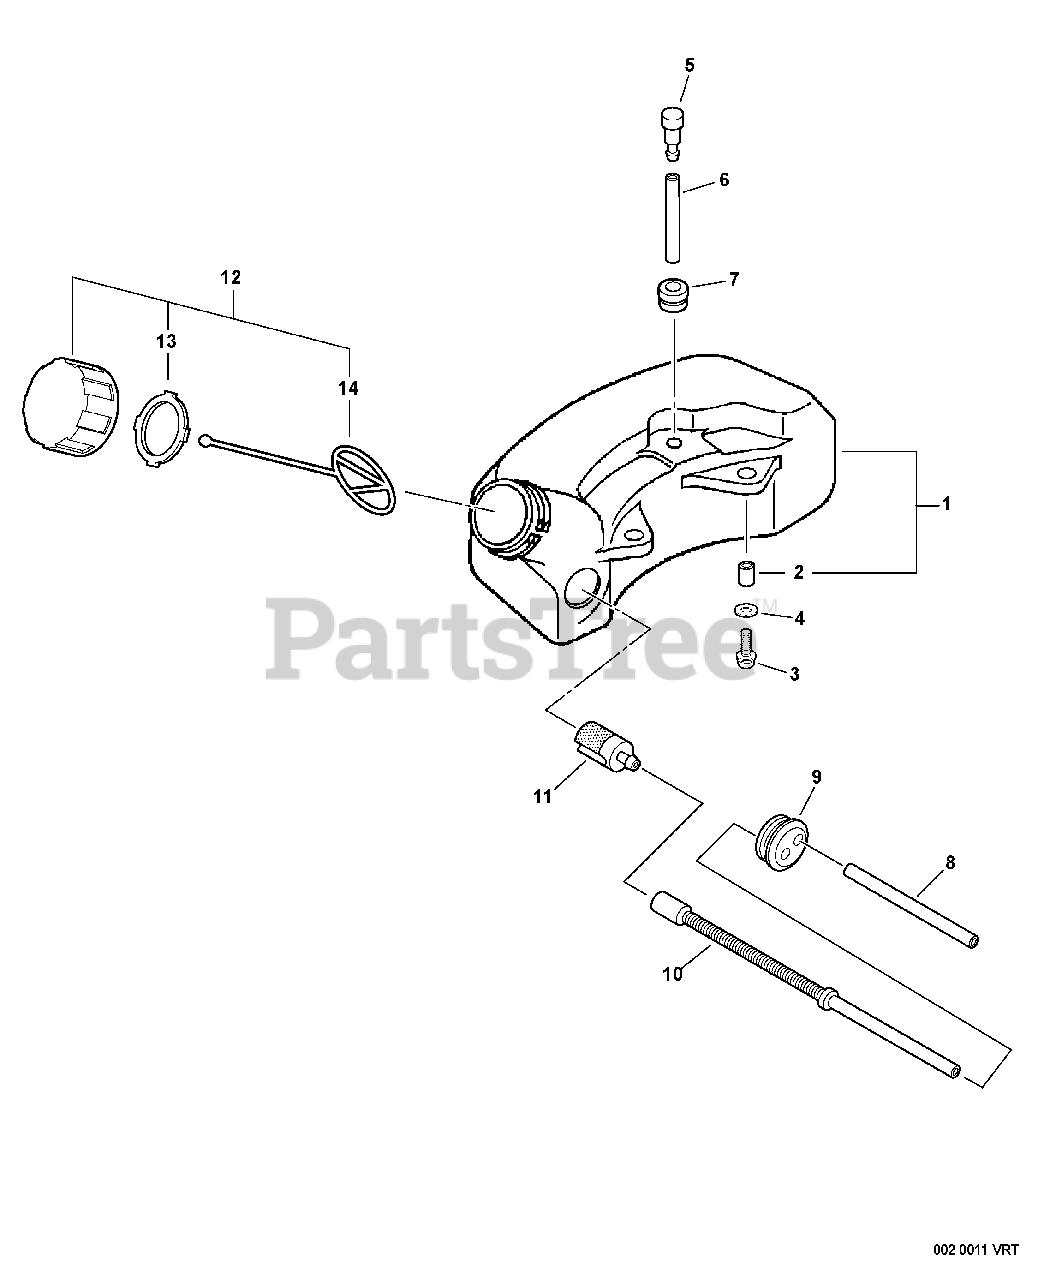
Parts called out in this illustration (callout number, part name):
1	TANK, FUEL
3	SCREW - 5X16
4	WASHER - 5
5	VENT, FUEL TANK
6	PIPE - 3X6X35 -- BLACK
7	GROMMET
8	PIPE - 3X6X110 -- CLEAR
9	GROMMET
10	PIPE, FUEL - CORRUGATED
11	FILTER, FUEL
12	CAP ASSY - ORANGE
13	GASKET, CAP
14	CONNECTOR, CAP
